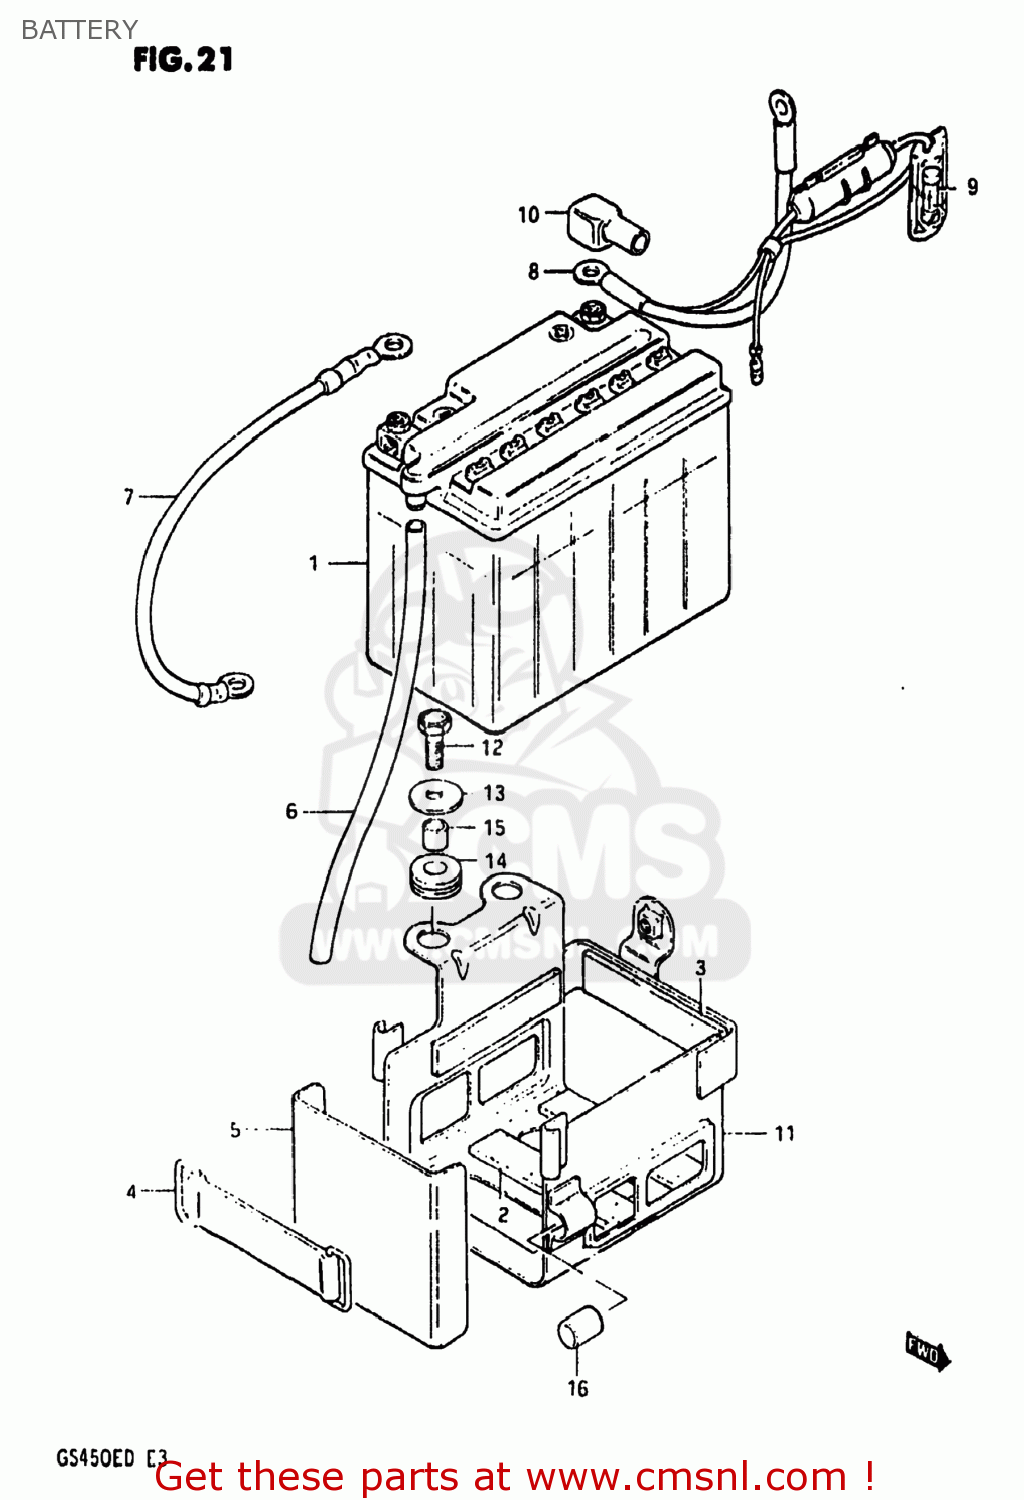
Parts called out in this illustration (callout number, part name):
1	BATTERY ASSEMBLY (12V)
2	PROTECTOR(20X90)X4
3	PROTECTOR,20X9
4	BAND
5	COVER,BATTERY
6	HOSE,BATTERY EXHAUST
7	LEAD WIRE,BATTERY(-)
8	FUSE CASE AND PLUS CABLE
9	FUSE(15A)
10	CAP,TERMINAL
11	HOLDER,BATTERY
12	BOLT
13	WASHER
14	CUSHION
15	SPACER (6.1X9X9)
16	CUSHION
